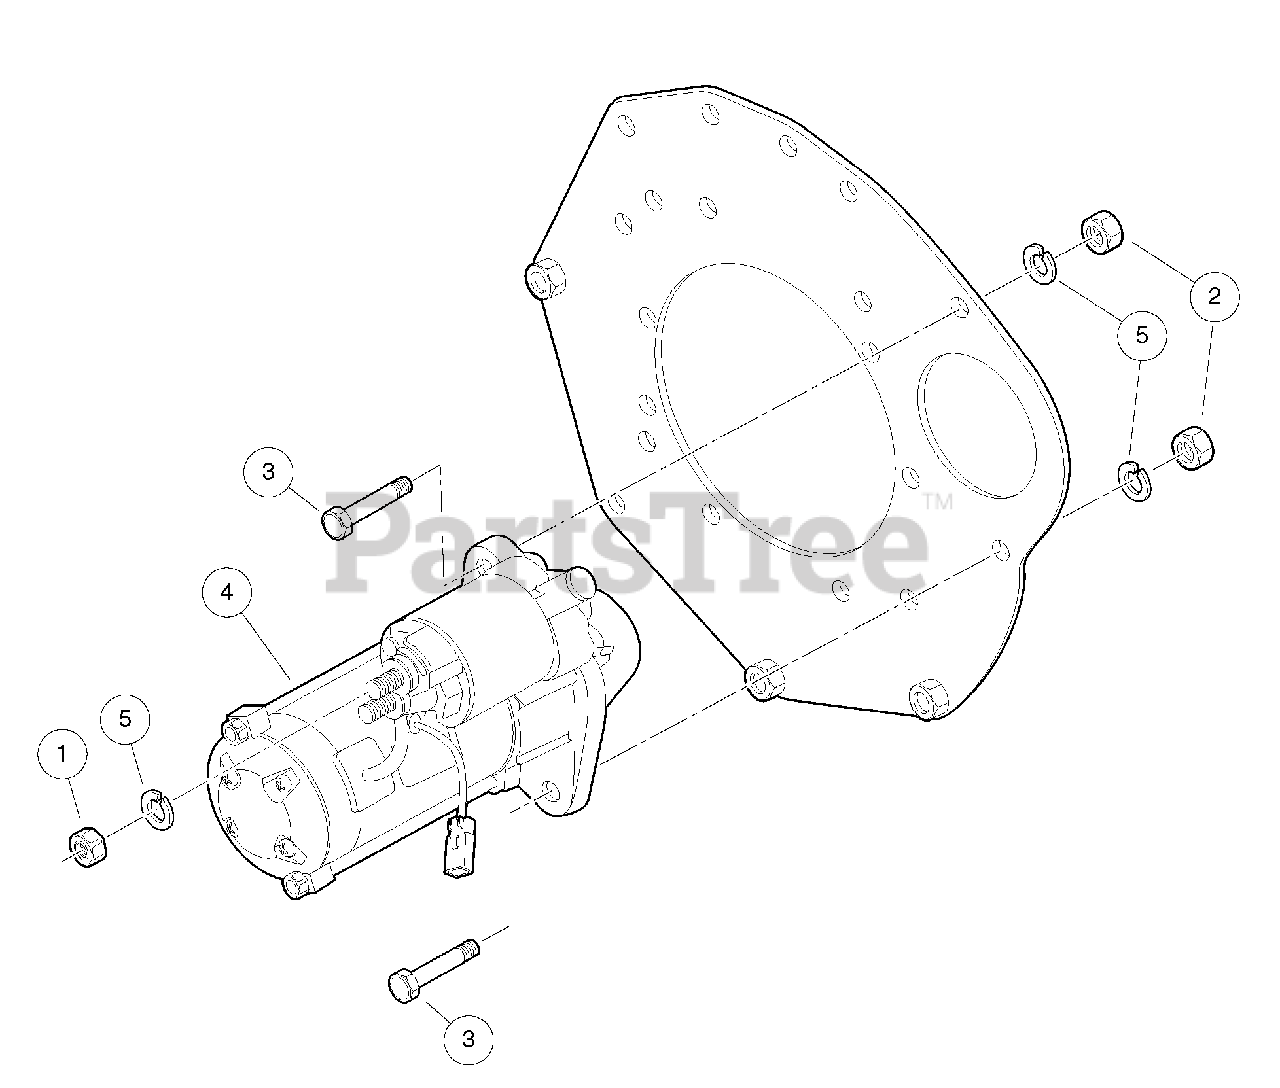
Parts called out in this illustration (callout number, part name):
1	Nut, D722, Starter
2	Nut, M8, Plate
3	Bolt, M8 X 1.25 X 28
4	Motor, Starter
5	Washer, Spring, D722, Starter
